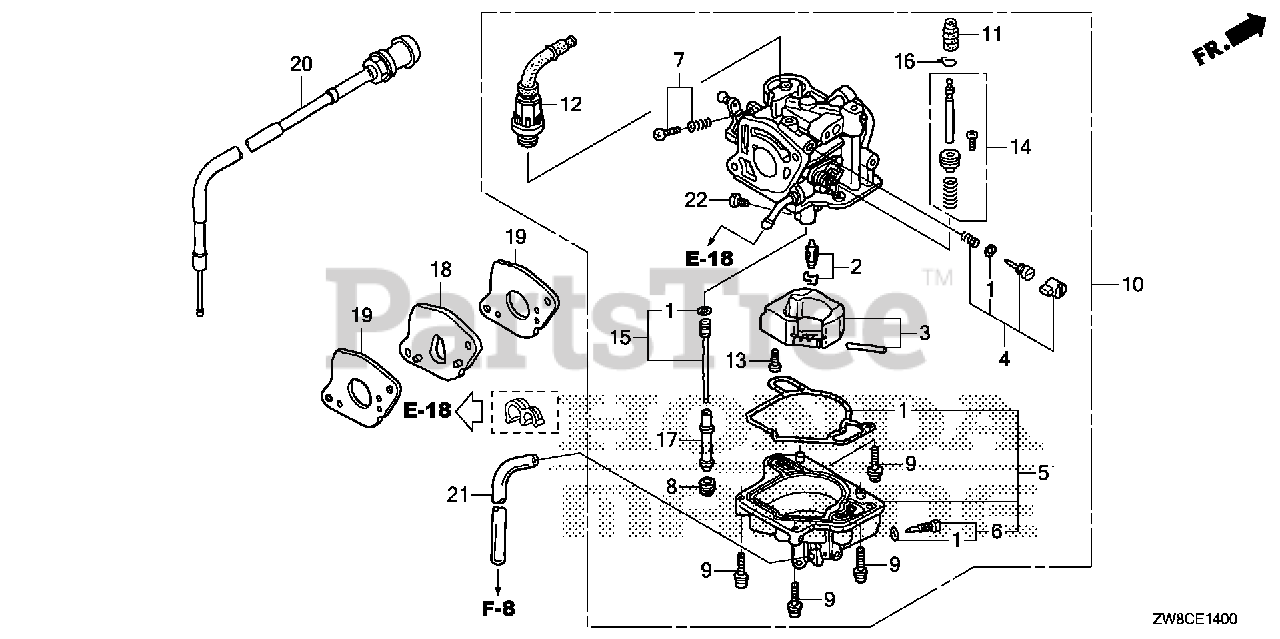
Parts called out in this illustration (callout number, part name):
1	GASKET SET
2	VALVE SET, FLOAT
4	SCREW SET
5	CHAMBER SET, FLOAT
6	SCREW SET, DRAIN (CARBURETOR NO.)
7	SCREW SET
8	SCREW, PLUG
9	SCREW-WASHER
10	CARBURETOR ASSY. (BJ05A D)
12	VALVE SET, STARTER
13	SCREW, PAN
14	PLUNGER SET, ACCELERATOR PUMP
15	JET SET (#45)
16	CLIP, TUBE
17	NOZZLE, MAIN
18	INSULATOR, CARBURETOR
19	GASKET, CARBURETOR
20	CABLE, CHOKE
21	BULK HOSE, VINYL (4X7X8000) (95003-07(95003-07001-60M) (CARBURETOR NO.)
22	JET, MAIN (#98)
22	JET, MAIN (#102)
22	JET, MAIN (#105)
22	JET, MAIN (#108)
